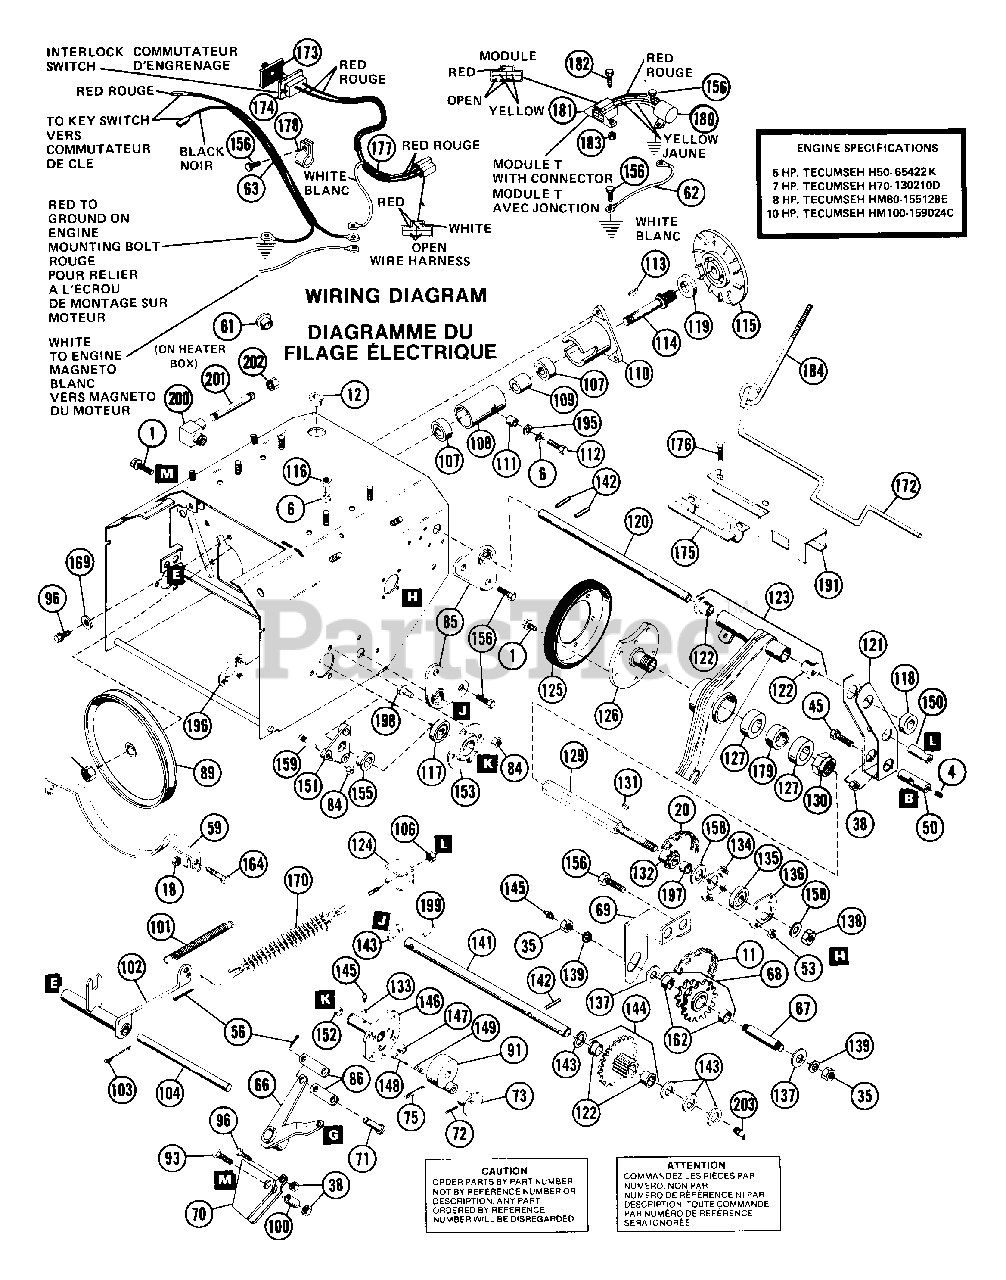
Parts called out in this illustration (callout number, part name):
1	BLT-SERHFWH .31-18X.50 PL
4	SCR-SET .32-18X.38 SKHCUPNL OH
6	WSHR-LK .312X.097 PL HVY
11	PINION CHAIN
12	SNAP BUSHING-.437
18	NUT-LK-CTR .250-20 PL
20	IDLER CHAIN
20	CHAIN
35	NUT-HEX .375-16
38	NUT-LK .312-18 GR A PL
45	BLT-HEX .31-18X.75 PL GR2
50	ROD ADAPTER
53	NUT-LK DUAL FACE 10-24 PL
56	PIN-COTR .09X.75 PL
59	BELT RETAINER
61	BUTTON PLUG 1.0
62	WIRE - GROUND
63	SHORTING WIRE
66	LEVER - SHIFT ARM
67	REDUCTION SHAFT
68	SPROCKET ASSY
69	SUPPORT, SHAFT
69	CLUTCH STOP
70	BRACKET SHIFT LEVER
71	CLEVIS PIN
72	PIN-ROLL .093X1.00
73	KNOB
75	PIN-GRV .250X1.75 TP C
84	NUT-LK-FLG .250-20 PL
85	SUPPORT, SHAFT
86	SHIFT LINK
89	PLY-V 8.00 X 1.0 W/KEY CLARK
90	NUT-LK-NYL.625-18 PL
91	LOCKOUT HUB
93	BLT-HEX .31-18X3.00 PL GR2
96	BLT-HEX .31-18X.50 PL GR2
100	SPACER .5 X .33 X 2.4
101	SG-TENS .080X.73X3.06 WLD 20
102	FORK, CLUTCH
103	PIN-COTR .09X1.0 PL
104	ROD, FORK PIVOT
106	NUT-LK-NYL.312-18 PL
107	BRG-BALL .625X1.375X.44
108	SPINDLE HOUSING
109	BEARING SPACER
110	DRIVE SPINDLE HOUSING
112	BLT-HEX .31-18X1.00 PL GR 2
113	KEY-WDRF .125X.500X.203 SAE 3
114	SPINDLE
115	DRIVE PLATE
116	NUT-HEX .312-18
117	BRG-BALL 1.13X2.18X.63
117	BRG-BALL .876 X 1.750 X .50
118	SPACER 1.00 X .64 X .38
119	DRIVE DISC SPACER 1.3X.76X.19
120	CARRIER SHAFT
121	CLUTCH ENGAGEMENT YOKE
122	BSHG-FLG .625X.750X.500X.875BR
123	DISC CARRIER SERVICE ASSEMBLY
124	ADAPTER SPACER
125	FRICTION DISC
126	FRICTION DISC HUB
127	BRG-BALL .876 X 1.750 X .50
129	HEX SHAFT
130	NUT-LK-NYL .875-14
131	KEY-WDRF .125X.625X.250 SAE5
132	9 TOOTH SPROCKET
133	WSHR-LK .250X.047 LT PL
134	BEARING FLANGE
135	BRG-BALL .500X1.38X.437
136	BEARING FLANGE
137	WSHR-FL-STL .382X.812X.062
138	NUT-LK-CTR .50-20 PL
139	WSHR-LK .375X.130
141	PINION SHAFT
142	PIN-ROLL .156X1.00
143	WSHR-FL-STL .630X1.005X.062 PL
144	PINION & SPROCKET
145	SPIN DRIVE ZERK FITTING
146	L H AXLE ASSEMBLY
147	BSHG-SLV .562X.625X.625 BRZ
148	PIN
149	SG-COMP .028X.34X1.062 WLD75
150	ADAPTER
151	SUPPORT, BEARING
152	BSHG-SLV .750X.814X .750 BRZ
152	BSHG-SLV .562X.625X.625 BRZ
153	BEARING FLANGE
153	BEARING RETAINER
155	BSHG-FLG .750X1.000X.625X1.250
155	BSHG-FLG.875X1X.625X1.250 BR
156	BLT-SERHFWH .25-20X.50 PL
158	WSHR-FL-STL .505X1.000X.062
159	SCR-SLTR-SERNK .25-20X.62 PL
162	BSHG-SLV .500X.625X.500 BR
164	BLT-HEX .25-20X.50 PL GR2
169	WSHR-LK-INT .313X.030 PL
170	SPRING ASSEMBLY
172	SWITCH ACTUATOR
173	SWITCH BOOT
175	ROD RETAINER
176	SCR-TAP 10-24X.375 HWH PL TR
177	WIRING HARNESS
180	MODULE T SERVICE ASSEMBLY
181	CONNECTOR
183	NUT-KEPS 10-24 PL
184	LOWER ROD INTERLOCK
191	SWITCH RETAINER
195	WSHR-FL-STL.344X.688X.065PL
196	BEARING FLANGE
198	BLT-SERNK SL .25-20X.50 PL
199	PIN-ROLL .125X1.00
200	STREET ELBOW
201	NIPPLE
202	HEX CAP
203	HYDRAULIC DRIVE FITTING
